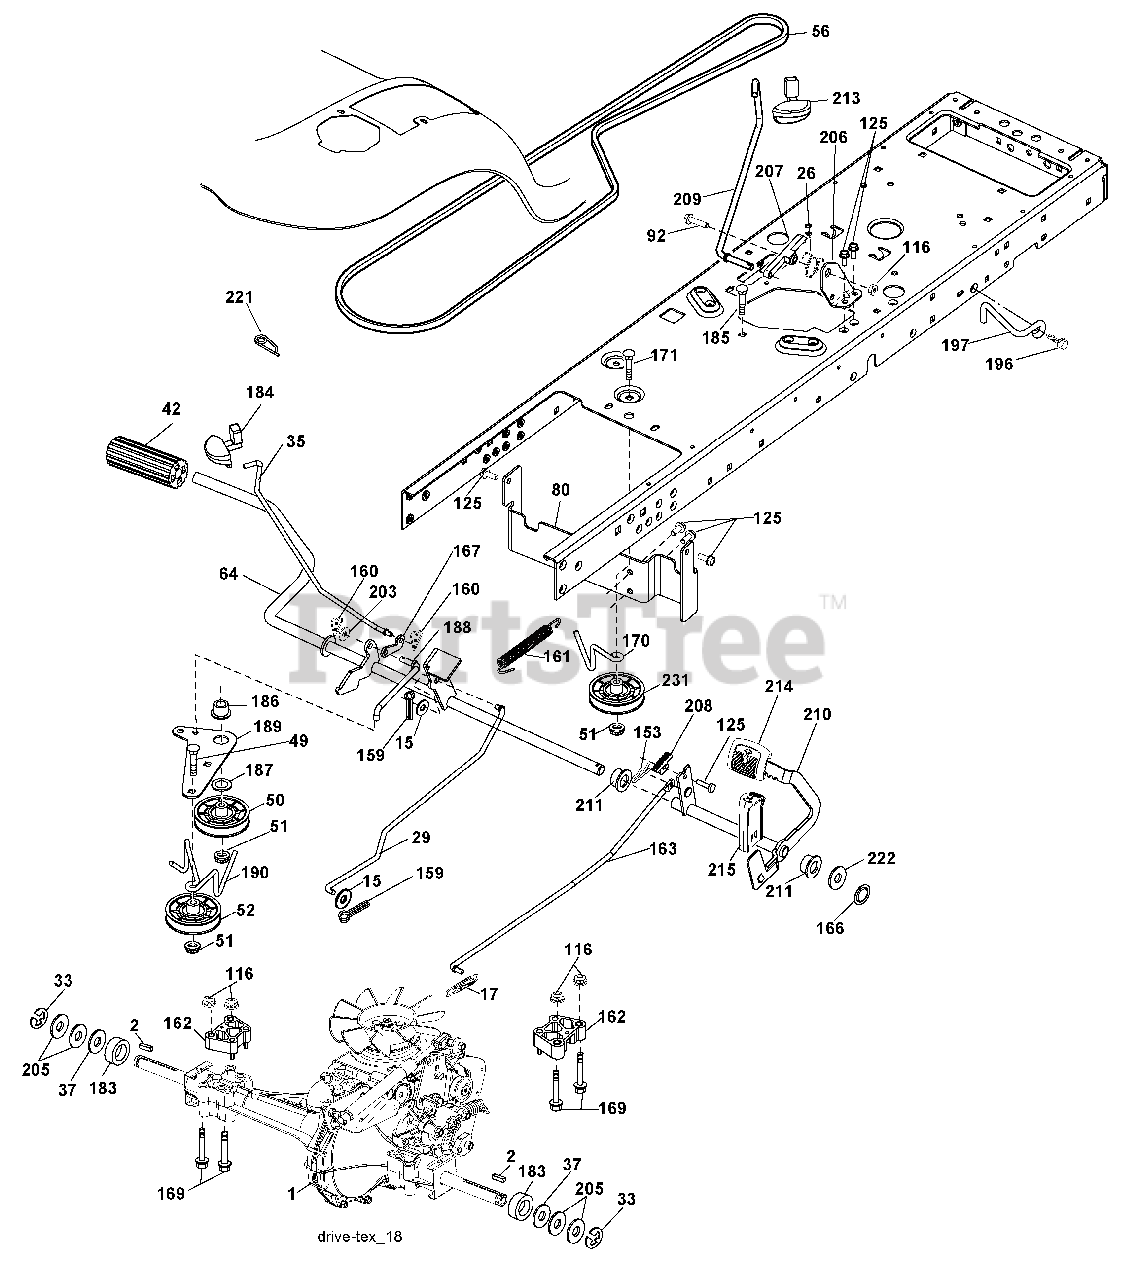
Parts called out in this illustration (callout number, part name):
2	Key
15	Washer 13/32 x 13/16 x 16 Ga.
17	Spring, Brake
26	Spring Return Cruise
29	Rod, Brake
33	Ring E
35	Rod, Brake, Park
37	Washer 25/32 x 1-1/4 x 16 Ga.
42	Cover, Foot Pedal
49	Bolt
50	Pulley Idler Flat
51	Lock Nut 3/8-16
52	Idler V-Groove 910" Offset
56	V-Belt, Drive
64	Shaft Asm. Pedal Brake Control
80	Bracket Strap Torque
92	Bolt Fin Hex 5/16-18 unc x 1.25
116	Nut Lock Hex Flange 5/16-18
125	Screw 5/16-18 x 3/4
153	Retainer Spring
159	Pin Cotter 1/8 x 3/4
160	Retainer Clip
161	Spring, Return, Clutch
162	Spacer Transaxle
163	Rod Pedal Control
166	Nut Push .625
167	Latch Brake Parking
169	Bolt Hex 5/16-18 x 3.75
170	Keeper Belt Centerspan
171	Bolt
183	Spacer Axle
184	Handle Parking Brake
185	Bolt
186	Spacer Retainer
187	Washer
188	Link Clutch Ground Drive
189	Bellcrank Ground Drive
190	Keeper Bellcrank Ground Drive
196	Screw 3/8-16 x 1
197	Link Clutch Anti Rotation
203	Washer 11/32 x 11/16 x 16 Ga.
205	Washer 25/32 x 1-5/8 x 16 Ga.
206	Bracket Mount Latch Cruise
207	Latch Control Cruise
208	Gear Sector Control Cruise
209	Rod Control Cruise
210	Rockr Asm. Pdeal Control
211	Bearing Nylon
213	Knob control Cruise
214	Pad Pedal Forward
215	Pad Pedal Reverse
222	Washer 21/32 x 1-1/4 10 Ga.
231	Idler V-Groove
